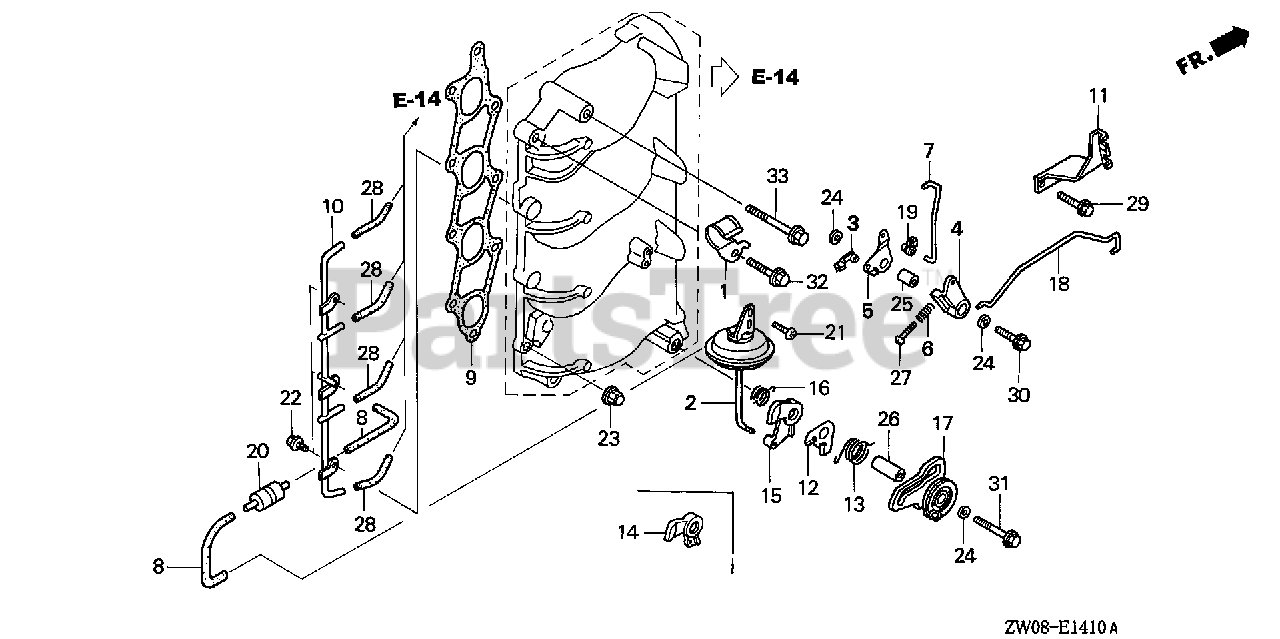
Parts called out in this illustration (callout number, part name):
1	CLAMP, TUBE
2	DIAPHRAGM ASSY.
3	JOINT, ROD
4	ARM A, CHOKE
5	ARM B, CHOKE
6	SPRING, CHOKE ARM ADJUSTING
7	ROD, CHOKE
8	TUBE, FUEL (D)
9	GASKET, IN. MANIFOLD
10	PIPE, INSTALL
11	STAY, THROTTLE CABLE
12	PLATE, ASSIST
13	SPRING, ASSIST
14	CAM, THROTTLE OPENER
16	SPRING, OPENER CAM RETURN
17	CAM, THROTTLE
18	ROD, CHOKE KNOB
19	BUSH, LINKAGE
20	VALVE, DASHPOT CHECK
21	BOLT, TORX (6X14)
22	BOLT, FLANGE (5X10)
23	NUT, FLANGE CAP (8MM)
24	WASHER, PLAIN (6MM)
25	COLLAR, DISTANCE (6.5X10.5X16)
26	COLLAR (6.7X12.5X31.5)
27	SCREW, PAN (4X16)
28	BULK HOSE, FUEL (3.5X3000) (3.5X120)
29	BOLT, FLANGE (6X16)
30	BOLT, FLANGE (6X30)
31	BOLT, FLANGE (6X45)
32	BOLT, FLANGE (8X35)
33	BOLT, FLANGE (8X70)
